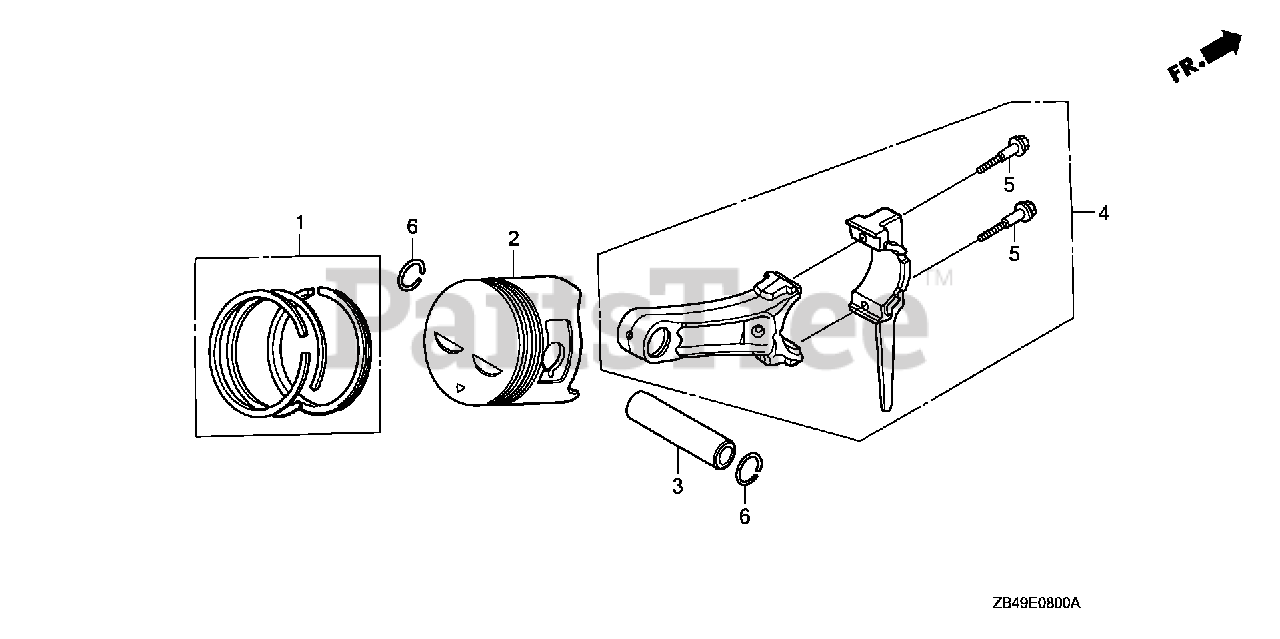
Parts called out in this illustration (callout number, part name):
1	RING SET, PISTON (STD) (NIPPON)
1	RING SET, PISTON (STD) (TEIKOKU)
1	RING SET, PISTON (0.25) (TEIKOKU)
1	RING SET, PISTON (0.25) (NIPPON)
1	RING SET, PISTON (0.50) (TEIKOKU)
1	RING SET, PISTON (0.50) (NIPPON)
1	RING SET, PISTON (0.75) (NIPPON)
1	RING SET, PISTON (0.75) (TEIKOKU)
2	PISTON (STD)
2	PISTON (0.25)
2	PISTON (0.50)
2	PISTON (0.75)
3	PIN, PISTON
4	ROD ASSY., CONNECTING (STD)
4	ROD ASSY., CONNECTING (0.25 LOWER SIZE)
5	BOLT, CONNECTING ROD
6	CLIP, PISTON PIN (18MM)
